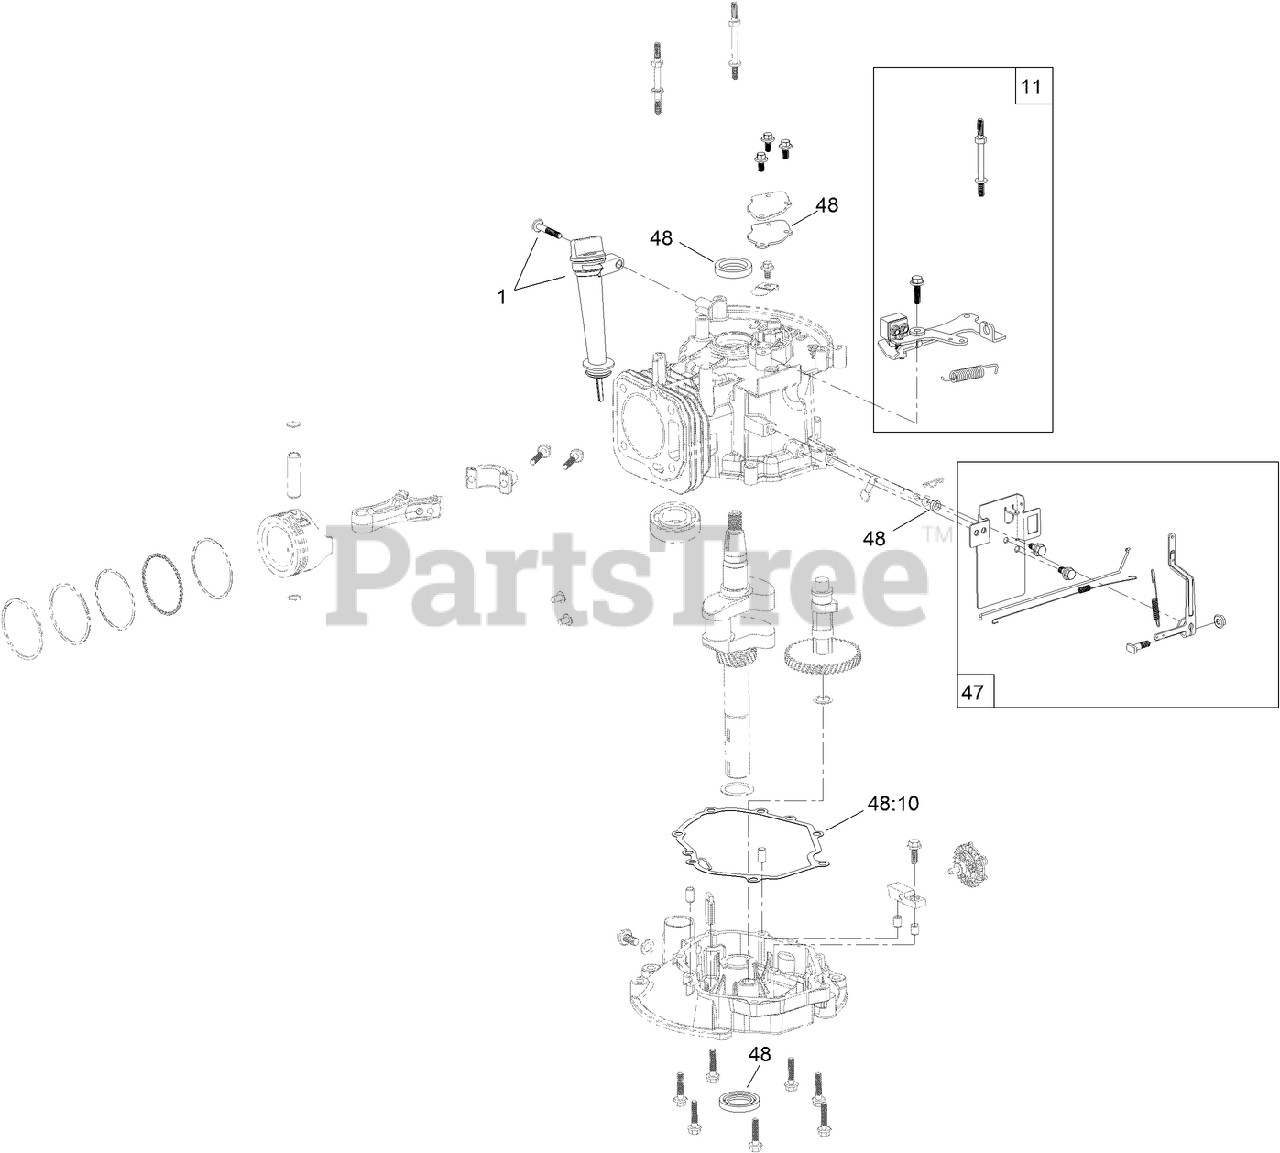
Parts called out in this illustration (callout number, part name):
1	DIPSTICK AND FILL TUBE KIT
11	BRAKE ASM RECOIL KIT
47	GOVERNOR ARM KIT
48	SEAL AND GASKET KIT
48:10	GASKET-VALVE COVER
